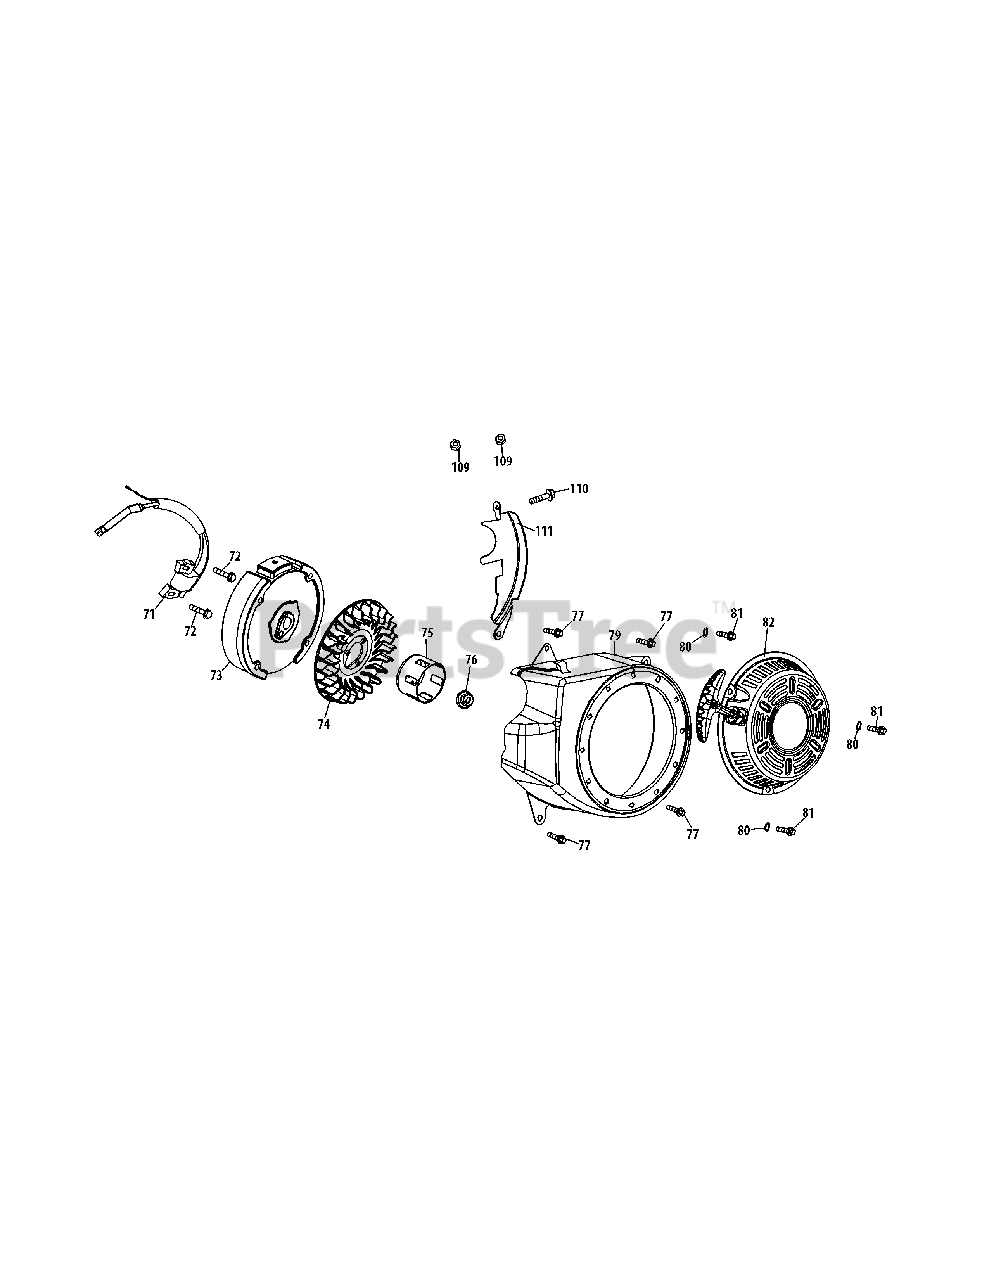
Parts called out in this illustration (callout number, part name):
71	Ignition Coil Assembly
72	Bolt M6×25
74	Fan, Cooling
75	Pulley, Starter
76	Nut, Special, M14×1.5
77	Bolt M6×12
79	Blower Housing
80	Washer, Flat
81	Bolt M6×10
82	Recoil Starter
109	Nut, M6
110	Bolt M6×20
111	Blower Housing Shield
